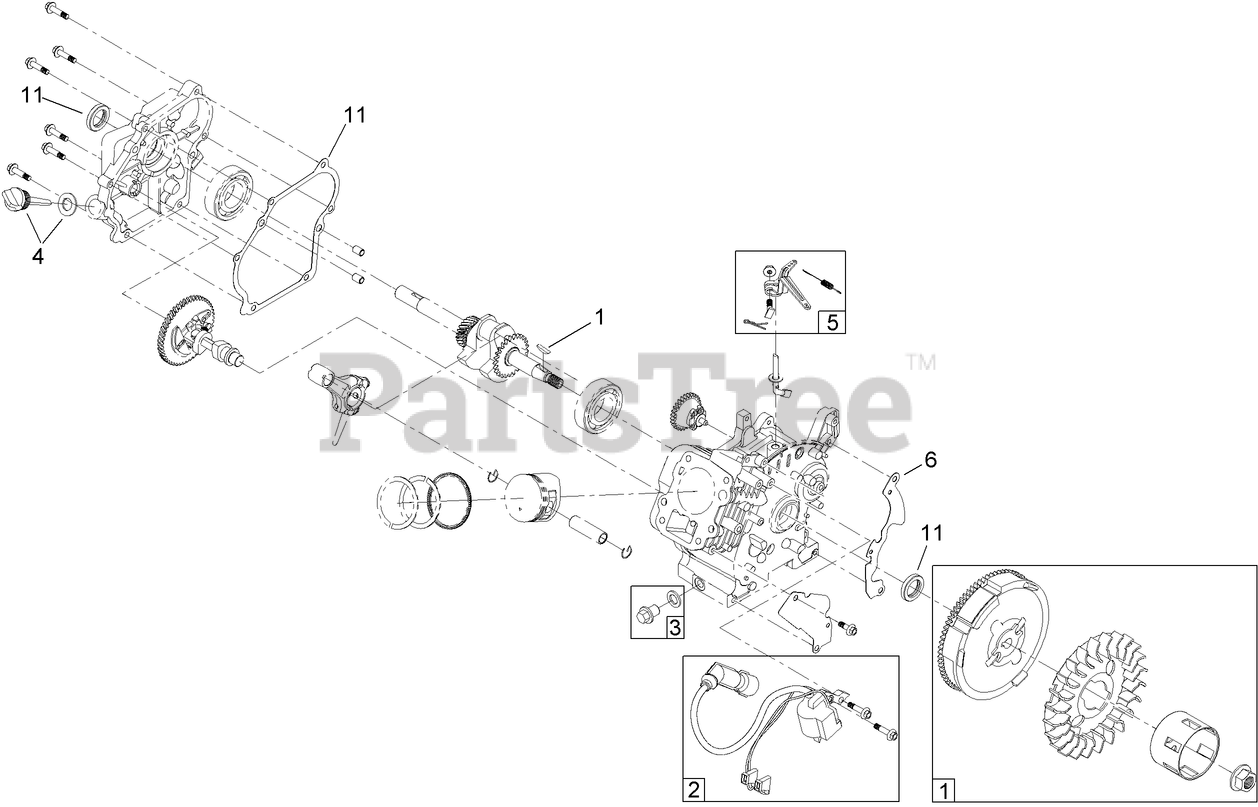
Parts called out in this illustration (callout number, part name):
1	FLYWHEEL KIT
3	DRAIN PLUG KIT
4	DIPSTICK AND O-RING KIT
5	GOVERNOR KIT
6	BLOWER SHROUD KIT
11	GASKET, SEAL AND O-RING KIT
